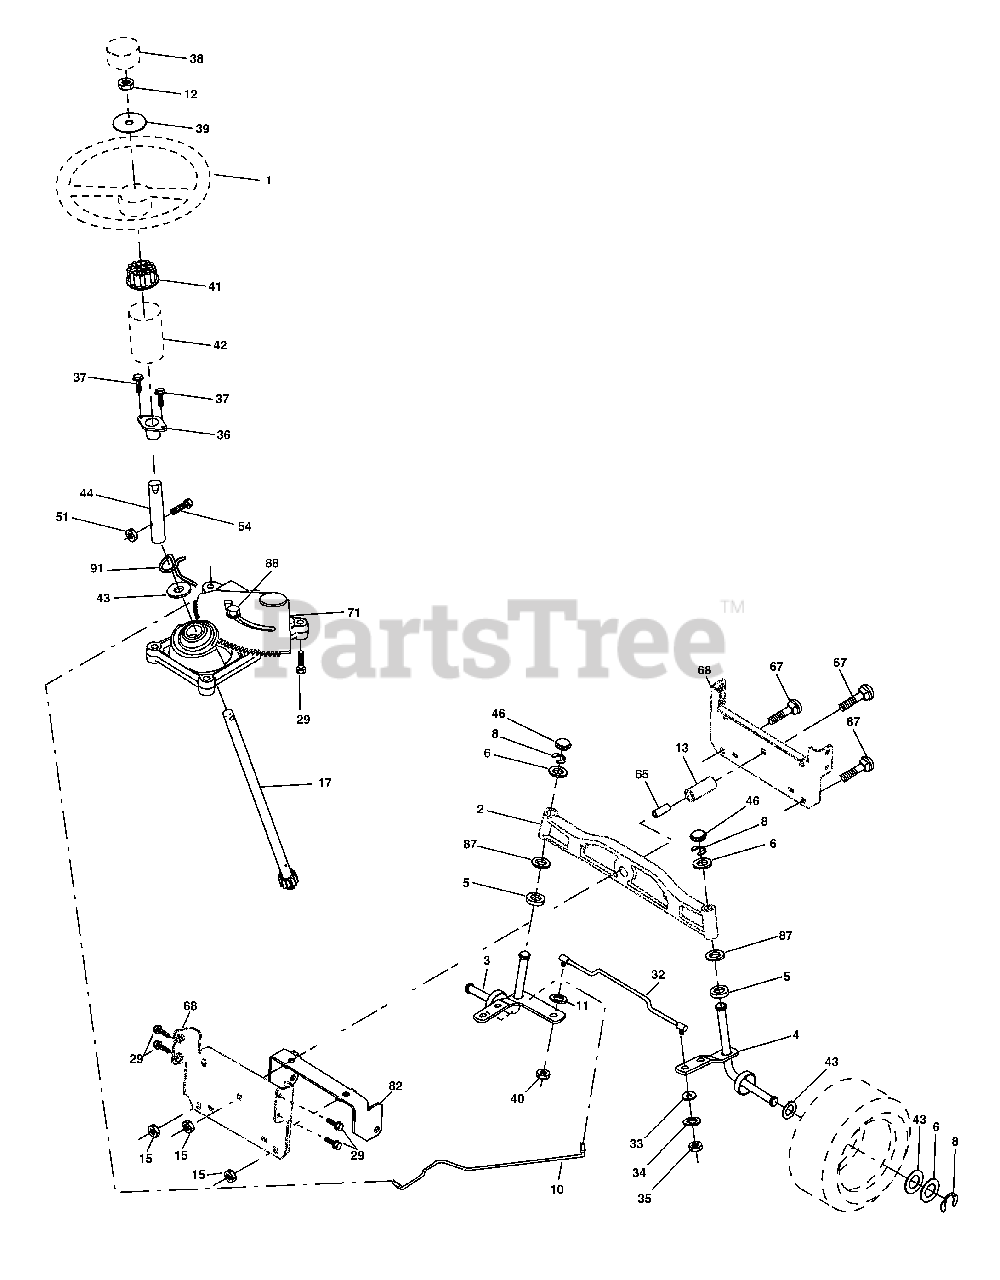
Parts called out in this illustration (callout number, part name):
1	Wheel Steering
2	Axle Asm Front
3	Spindle Asm Lh
4	Spindle Asm Rh
5	Bearing Race Thrust Harden
6	Washer 25/32 x 1 5/8 x 16ga
8	Ring Klip #t5304-75
10	Link Drag Extended
11	Lockwasher
12	Nut Hex Jam Toplock 1/2-20 Unf
13	Spacer Bearing Axle Front
15	Hex Flange Lock
17	Shaft Asm Strg
29	Screw 3/8-16x3/4
32	Rod Tie
33	Washer 11/32 x 3/4 x 16 Ga.
34	Washer lock 5/16
35	Nut Crownlock 5/16-24
36	Bushing Strg 5/8 Id Dash
37	Screw TT #10-32 x 5 x 3/8 Flange
38	Insert Cap Strg
39	Washer 9/16 ID x 1-1/2 OD 11 Gr
40	Locknut Center
41	Adaptor Wheel Strg
42	Boot Dash Steering
43	Washer 25/32 x 1 1/4 x 16 Ga
44	Extension Steering
46	Cap Spindle Fr Top Blk
51	Nut Crownlock 1/4-28
54	Bolt Hex 1/4-28 Unf x 1-1/4 Gr. 8
65	Spacer Brace Axle
67	Bolt Rdhd Sq 3/8-16 Unc x 2-3/4
68	Brace Axle
71	Steering Asm
82	Bracket Susp Chassis Front
87	Washer Flat
88	Bolt Shoulder 7/16-20
91	Clip Steering
